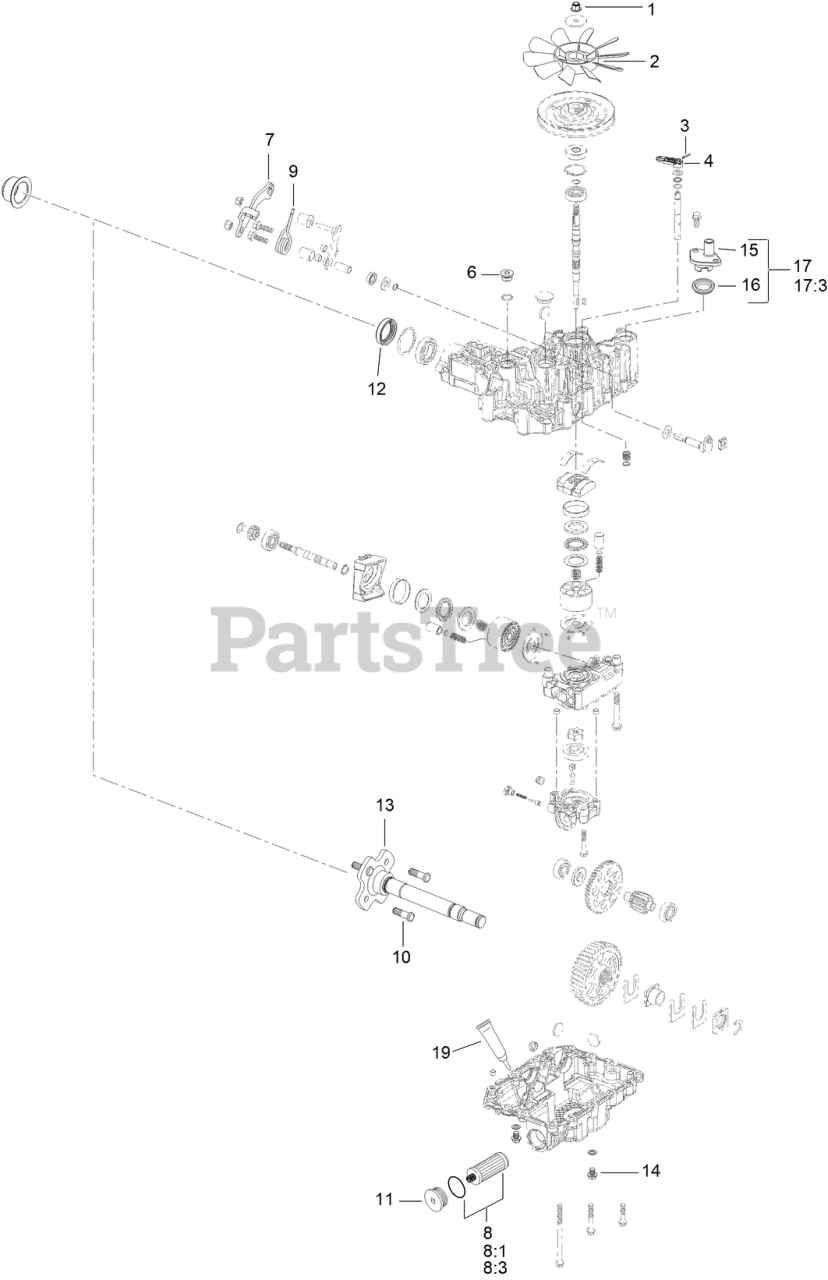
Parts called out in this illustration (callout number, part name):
1	NUT-LOCK
4	LEVER-BYPASS
6	CAP-OIL
7	LEVER-CONTROL, LH
8	2 TRANSMISSION FILTER KIT
8:3	SEALING WASHER
9	SPRING-TORSION
10	STUD-WHEEL
11	CAP-OIL FILTER
12	SEAL-AXLE, UA
14	DRAIN BOLT
15	EXPANSION FITTING
16	GROMMET SEAL, EXPANSION FITTING
17	EXPANSION FITTING - W/ SEAL
17:3	M8*20 FLANGE BOLT
19	KIT-SEAL, HYDRO
